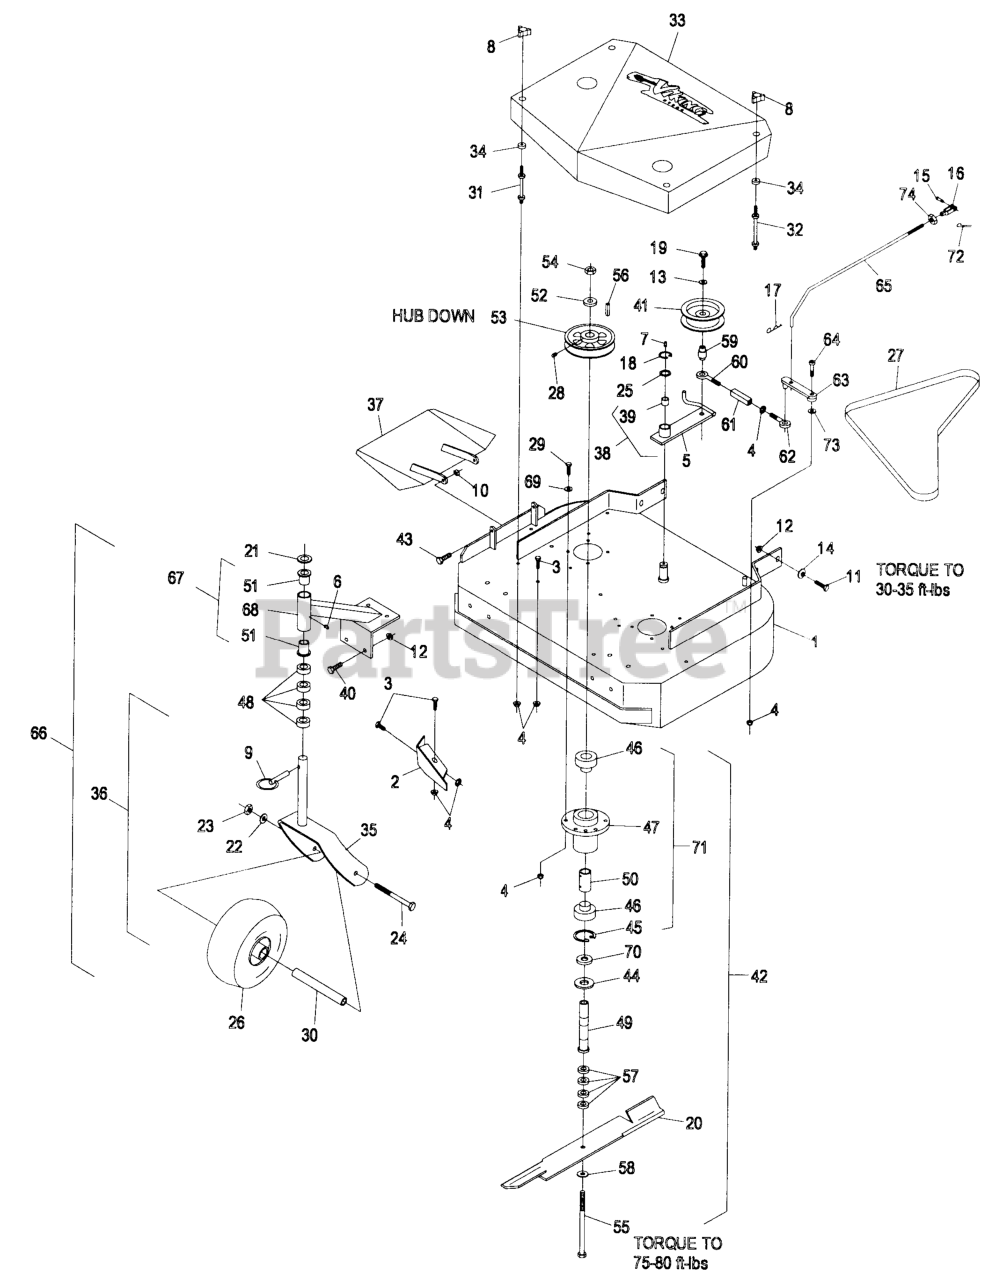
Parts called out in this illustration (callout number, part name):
2	BAFFLE-DOGLEG
8	KNOB-3 PRONG
15	PIN-CLEVIS
16	YOKE-ADJUSTABLE
17	PIN-COTTER
21	WASHER-FLAT
25	WASHER-SPINDLE
27	BELT,DECK DRIVE
28	SCREW-SET
31	STUD-SHIELD, BELT (SHORT)
32	STUD-SHIELD, BELT (LONG)
37	WLD,CHUTE 36 RIGID
39	BEARING,POWDERED METAL
42	HOUSING,CUTTER COMPLETE(S
44	GUARD-BEARING, BOTTOM
46	BEARING
48	SPACER-CASTER
49	TUBE-SPINDLE, SHORT
50	SPACER-BEARING
51	BEARING-FLANGED
52	WASHER-RETAINER, SHEAVE
55	SCREW-CAP, HH
58	WASHER-SPRING
59	BUSHING-ENGAGEMENT
60	EYEBOLT-THREAD, LH
61	BODY-TURNBUCKLE
62	EYEBOLT-THREAD, RH
64	BOLT,SHLDR KSKH 3/8 X 1
65	ARM-LINKAGE, ASSIST
66	CASTER/MOUNT ASM
67	SUPPORT ASM
69	WASHER-SPRING
70	SPACER-PULLEY/BEARING
